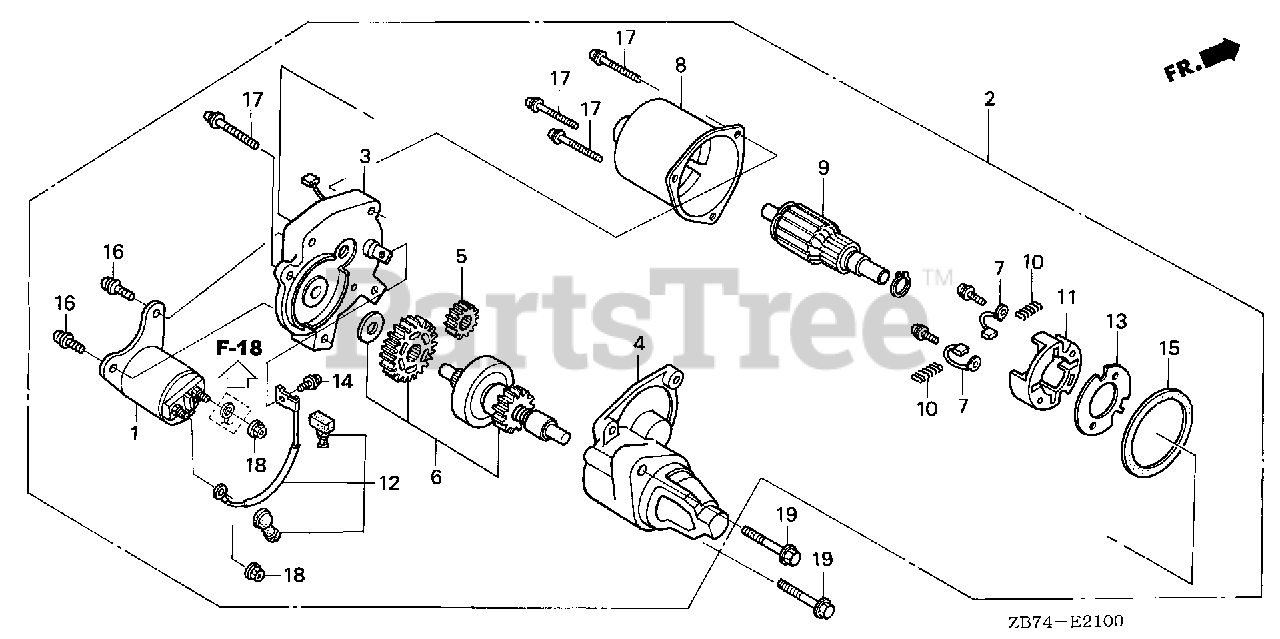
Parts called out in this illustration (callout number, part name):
1	CONTACTOR ASSY.
2	STARTER MOTOR UNIT
3	BRACKET, CENTER
4	BRACKET, FR.
5	GEAR, DRIVE PINION
6	CLUTCH, OVERRUNNING
7	BRUSH
8	YOKE
9	ARMATURE
10	SPRING, BRUSH RETURN
11	HOLDER, BRUSH
12	WIRE, WATER COVER
13	INSULATOR
14	SCREW-WASHER (4X6)
15	GASKET
16	BOLT-WASHER (5X14)
17	SCREW-WASHER (5X3)
18	NUT-WASHER (6MM)
19	BOLT, FLANGE (8X40) Use up to Engine SN 1003236.
